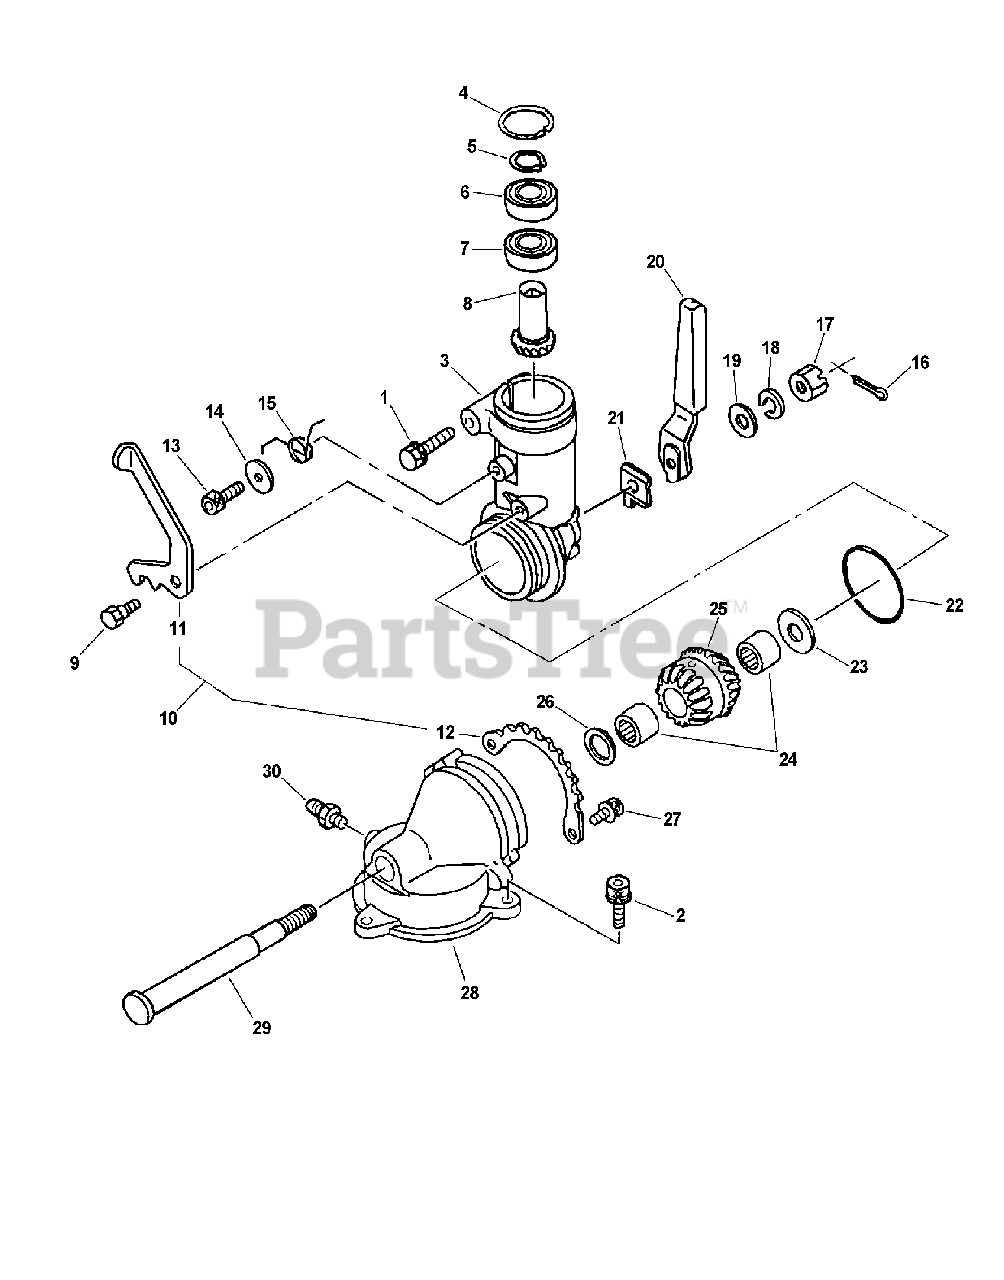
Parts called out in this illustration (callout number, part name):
1	BOLT - 5X35
2	SCREW - 5X18
3	CASE, GEAR
4	RING, RETAINING - 22
5	RING, RETAINING - 10
6	BEARING, BALL - 6900Z
7	BEARING, BALL - 6900
8	GEAR - DRIVE
9	BOLT - 5
10	LATCH RESETTER SET
12	RESETTER, LATCH
13	SCREW - 5X14
14	WASHER - 5
16	PIN, SPLIT - 1.6X16
17	NUT - 6 -- SLOTTED
18	LOCKWASHER - 6
19	WASHER, THRUST
20	PIECE, LEVER
21	PLATE, ANGLE
22	O-RING - 32
23	WASHER - 8
24	BEARING, NEEDLE - 8
25	GEAR - BEVEL
26	WASHER - 10
27	SCREW - 4X10
28	LID, GEAR CASE
29	GEAR - SHAFT
30	FITTING, GREASE
